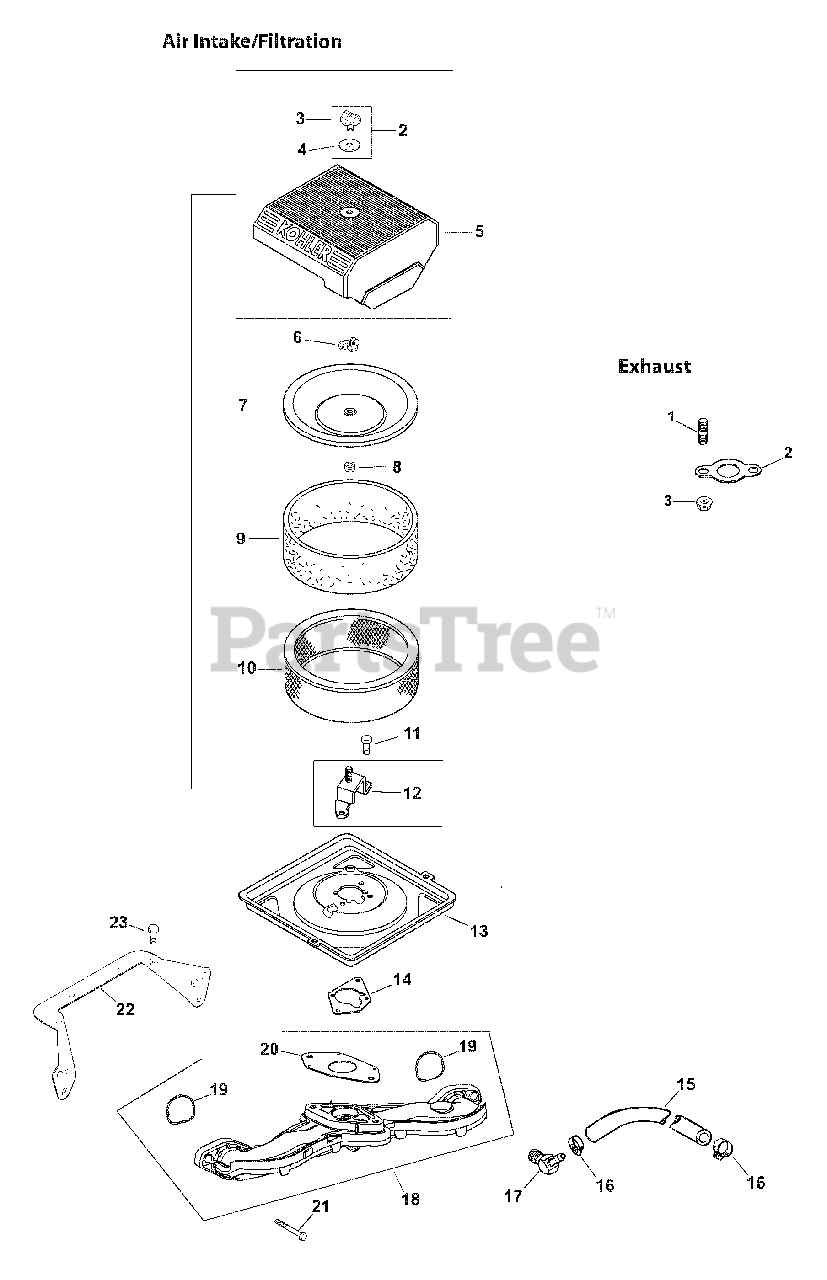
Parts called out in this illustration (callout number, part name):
1	Kit, air cleaner cover
2	Kit, knob with seal
3	Knob, cover
4	Seal, air cleaner cover knob
5	Cover, air cleaner
7	Cover, inner air cleaner
8	Seal, inner air cleaner
9	Precleaner, element
10	Element, air cleaner
11	Screw, hex. flange M6x1.0x16
12	Bracket, air cleaner base
13	Base, air cleaner
14	Gasket, air cleaner base
15	Line, fuel
16	Clamp, hose
17	Connector, pulse fitting
18	Manifold, intake
19	O-Ring, intake port
20	Gasket, carburetor
21	Screw, hex. flange M6x1.0x40
22	Bracket, air cleaner
23	Screw, hex. flange M5x0.8x10
